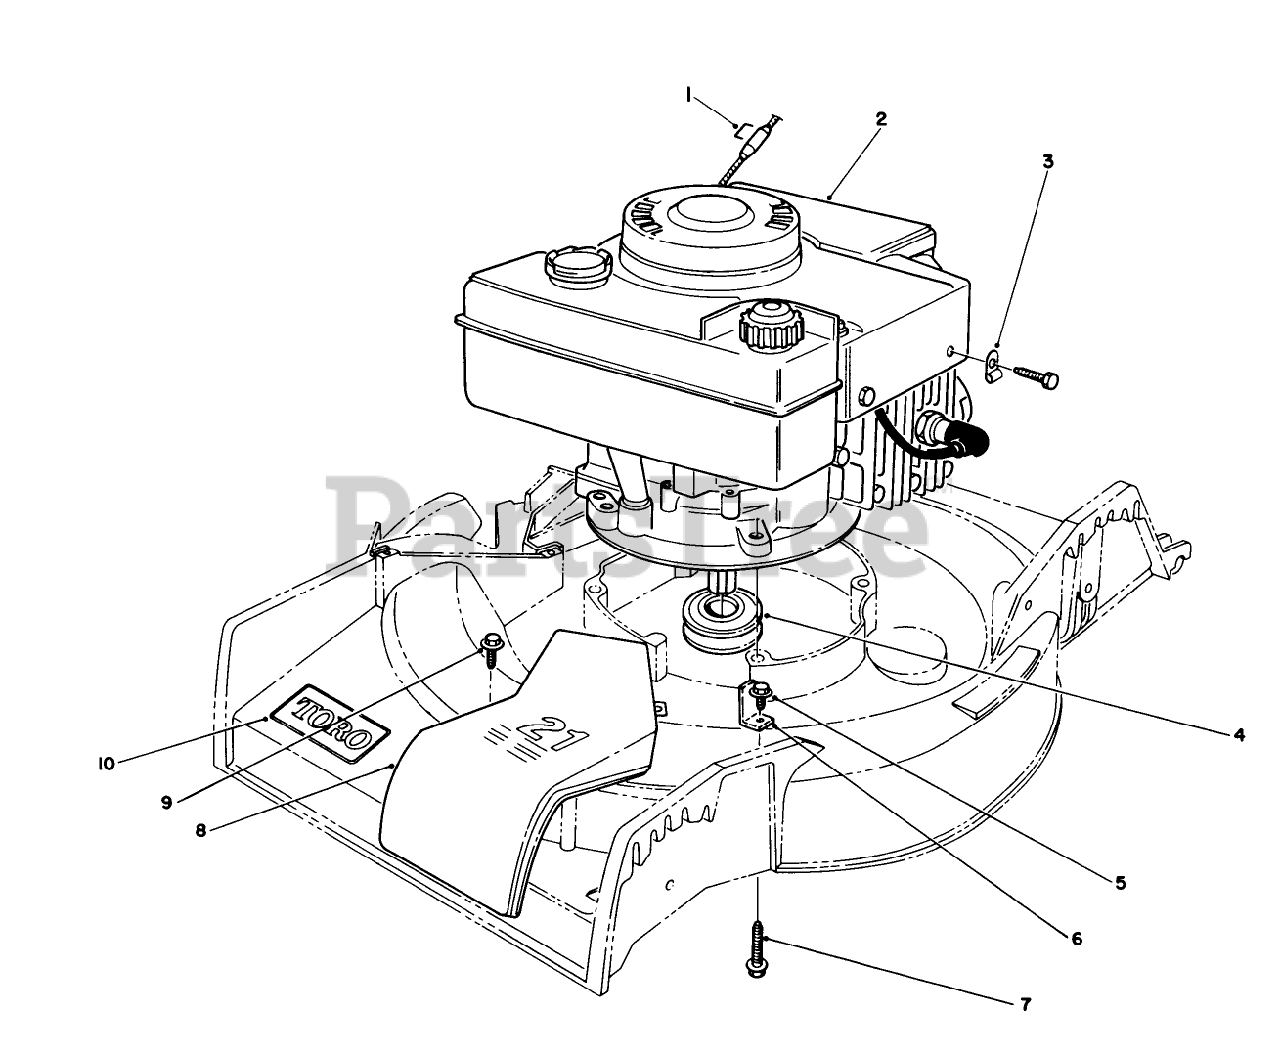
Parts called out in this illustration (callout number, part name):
1	Staple
2	Engine
4	PULLEY-DRIVER
5	SCREW-HWHTF
6	BELT GUIDE
7	3/8-16 X 2-3/4 CAPSCR
8	BELT COVER 21" S D
9	SCREW
10	DECAL
